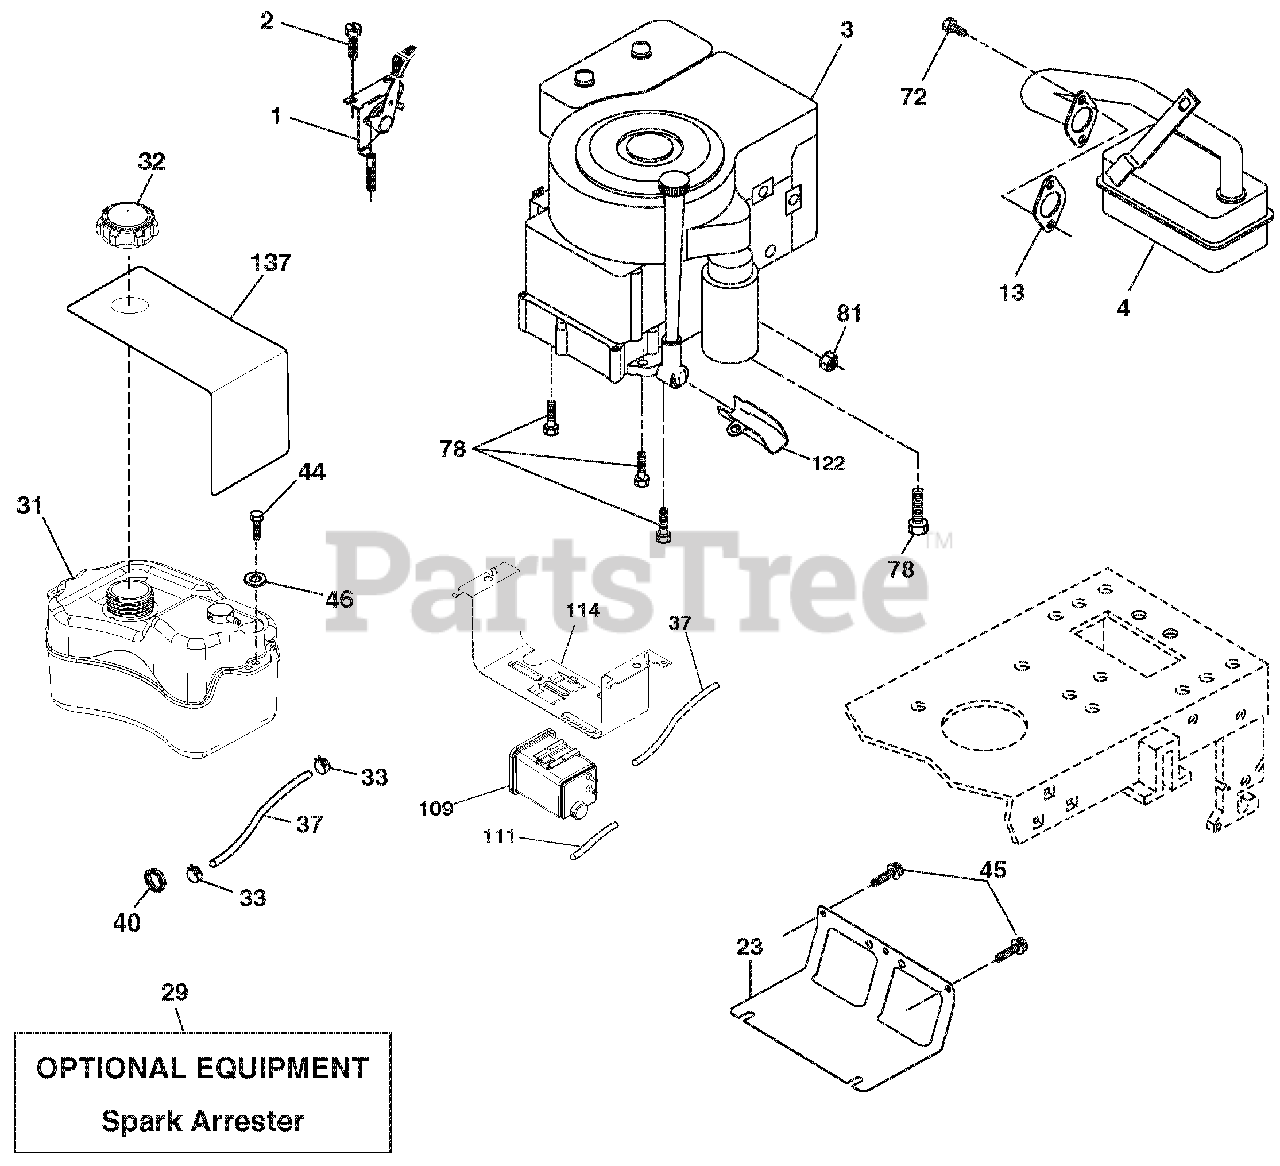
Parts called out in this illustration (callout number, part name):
1	Control Th/ch Flag
2	Screw 1/4-20 x 1/2
3	ENGINE, B&S 31R907-0019-G1(586044701) (ORDER PARTS FROM ENGINE MANUFACTURER.)
4	Muffler Exhaust B&S
13	Gasket Eng 1 313 Id Tin Plated
23	Shield BRN/DBR Guard
29	KIT.SPARK ARRESTOR(392390 B&S)
31	TANK ASM.FUEL.1.50.CARB.CA.SVC
32	CAP FUEL
33	CLAMP.HOSE.BLK.
37	LINE.FUEL.22"FRONT.EMIS.CA.LP
40	Bushing Snap Nyl Blk Fuel Line
44	SCREW.HEXWSH.THDROL.1/4-20X3/4
45	SCREW.HEXWSH THDR3/8-16X3/4.BL
46	WASHER.9/32 X 7/8 X 16GA.
72	SCREW.SOCKET HD.5/16-18 X .75
78	Screw 3/8-16 x <
81	Nut, Keps Hex 1/4-20 unc
109	CANISTER.CARBON.FILTER ASM.TEX
111	PURGE.LINE.CARB
114	CRADLE.CANISTER.CARBON
122	Extension Drain Oil
